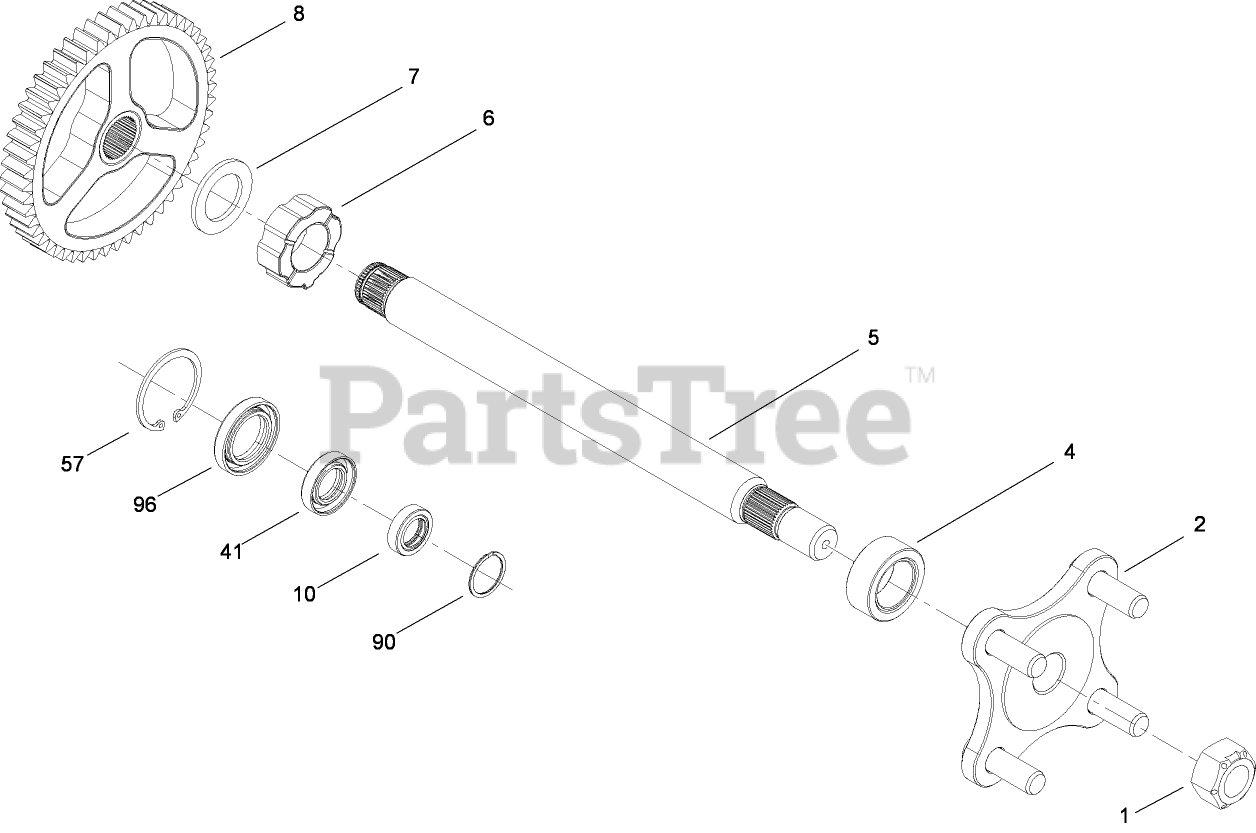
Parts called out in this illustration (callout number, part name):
2	HUB ASM
4	BUSHING-AXLE
5	SHAFT-AXLE
6	SLEAVE-BUSHING, INBOARD
7	WASHER
8	GEAR-52T, BULL
10	SEAL-LIP
41	SEAL-LIP
57	RING-RETAINING
90	RING-SPIRAL, RETAINING
96	SEAL-LIP
